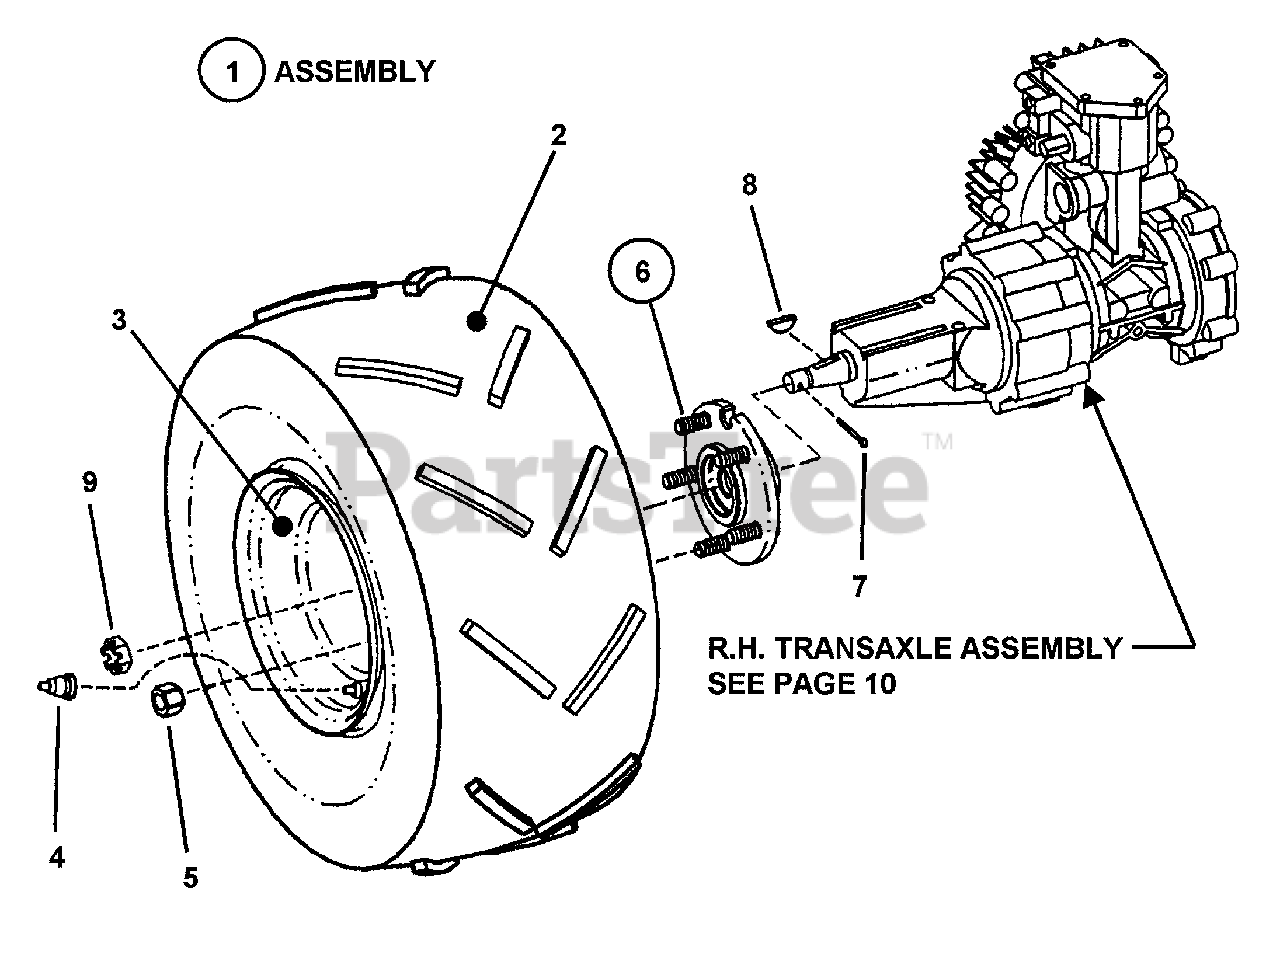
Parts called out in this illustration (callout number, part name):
2	TIRE, 21 x 11.00-8 4 ply "All Terrain"
3	RIM, 8" Dia. X 7-3/4"
4	VALVE, Air
5	NUT, 1/2-20 Lug
6	ASSEMBLY, Wheel Hub
7	PIN, Cotter, 9/64 x 1-1/2"
8	KEY, #806 Woodruff
9	NUT, 3/4-20 Slotted Hex
